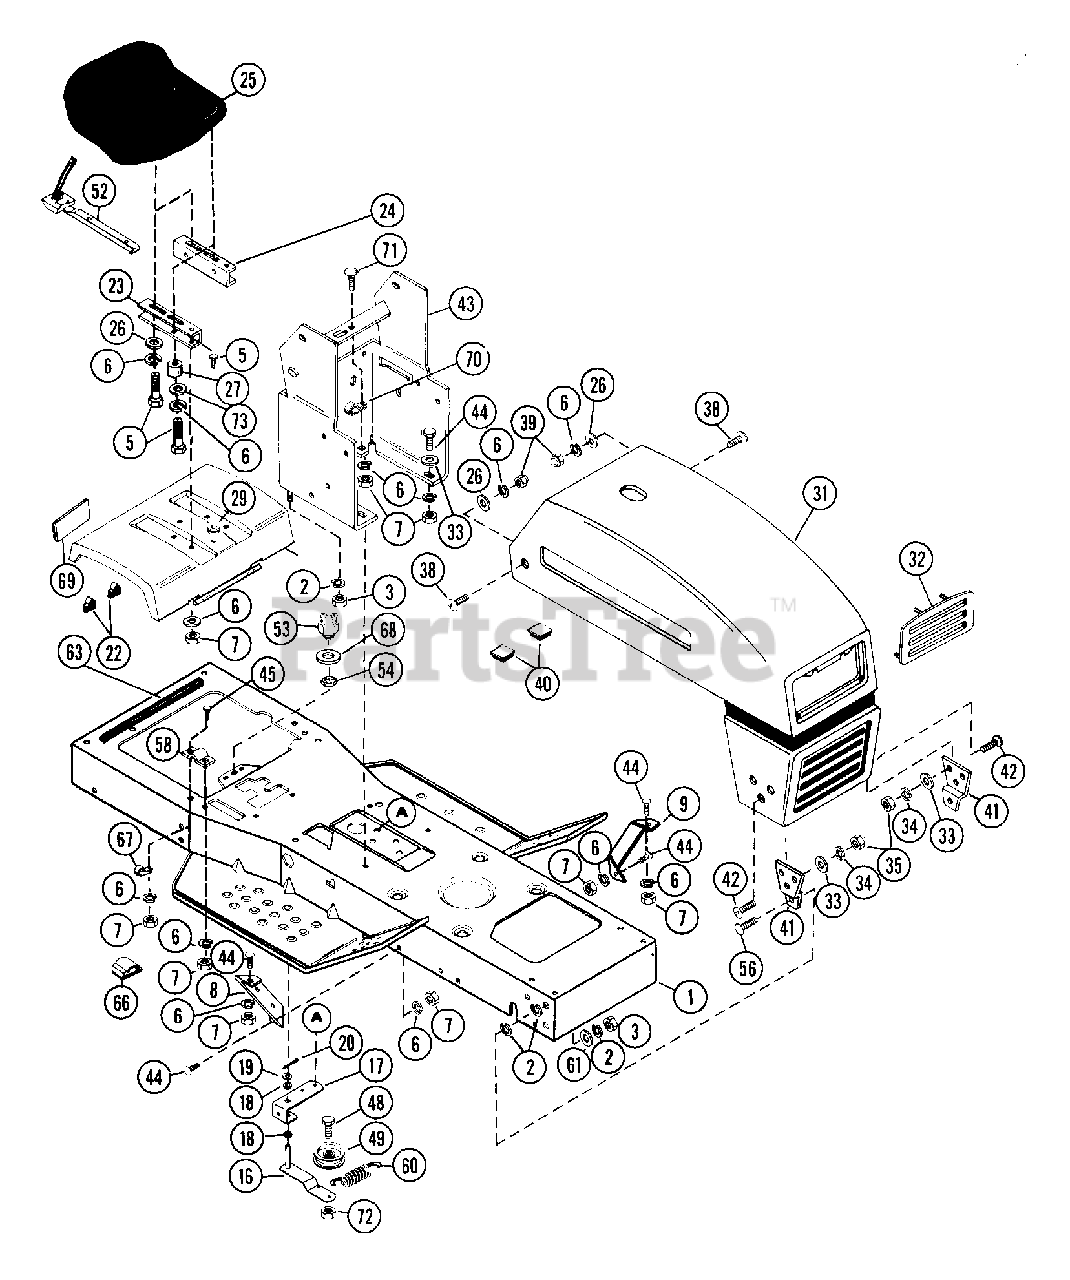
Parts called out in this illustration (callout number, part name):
1	FRAME W/DECALS
2	WSHR-LK .375X.094 MED PL
3	NUT-HEX .375-16
5	BLT-HEX .31-18X.75 PL GR5
6	WSHR-LK .312X.097 PL HVY
7	NUT-HEX .312-18
8	STRUT RIGHT FOOT BOARD
9	STRUT LEFT FOOT BOARD
10	BLT-RDHDSQNK .31-18X.75 GR5 PL
16	IDLER ARM
17	IDLER PIVOT
18	BSHG-FLG .372X.500X.312X.625NY
19	WSHR-FL-STL.406X.812X.065PL
20	PIN-COTR .12X1.0 PL
21	REAR DECK
23	SEAT CHANNEL R H
24	SEAT CHANNEL L H
25	SEAT
26	WSHR-FL-STL .38X.875X.083 PL
27	SPACER BUSHING .5 X .32 X .21
29	GROMMET, .31 ID
31	HOOD & GRILLE W/DECALS
32	GRILL INSERT
33	WSHR-FL-STL.312X.734X.065PL
34	WSHR-LK .250X.077 HVY PL
35	NUT-HEX .250-20 PL
38	SCR-MCH .31-18X.50 SLTR PL
39	NUT-CROWN .312-18 PL
40	STOP
41	HOOD HINGE
42	SCRW-MCH .25-20X.38 TRUSS PL
43	DASH BASE
44	BLT-RDHDSQNK .31-18X.75 GR5 PL
45	BLT-HEX .31-18X.75 PL GR2
47	SCR-MCH 10-24X.50 SLTR PL
48	BLT-HEX .38-16X1.50 PL GR5
49	IDLER-FLAT 2.75 X .38 DAYCO
50	WSHR-LK 10X.047 MED PL
51	NUT-HEX 10-24 PL
52	SWITCH SEAT
53	SWITCH-NEUTRAL START N.O.
54	NUT- .562-18
56	BLT-RDHDSQSHNK .38-16X1.00 PL
60	SG-TENS .080X.470X4.88 WLD 30
61	WSHR-FL-STL .438X1.0X.083 PL
62	WSHR-LK-EXT .313X.030 PL
63	1/4 X 3/4 X 1 IN FOAM TAPE
64	NUT-LK .375-16 PL
66	WIRE CLIP
68	WSHR-FL-STL .811X1.25X.005
69	REFLECTOR
71	BLT-RDHDSQNK .31-18X1.00 PL
72	NUT-LK TOP .375-16 GR C YWZC
73	WSHR-FL-STL .505X.875X.024 PL
